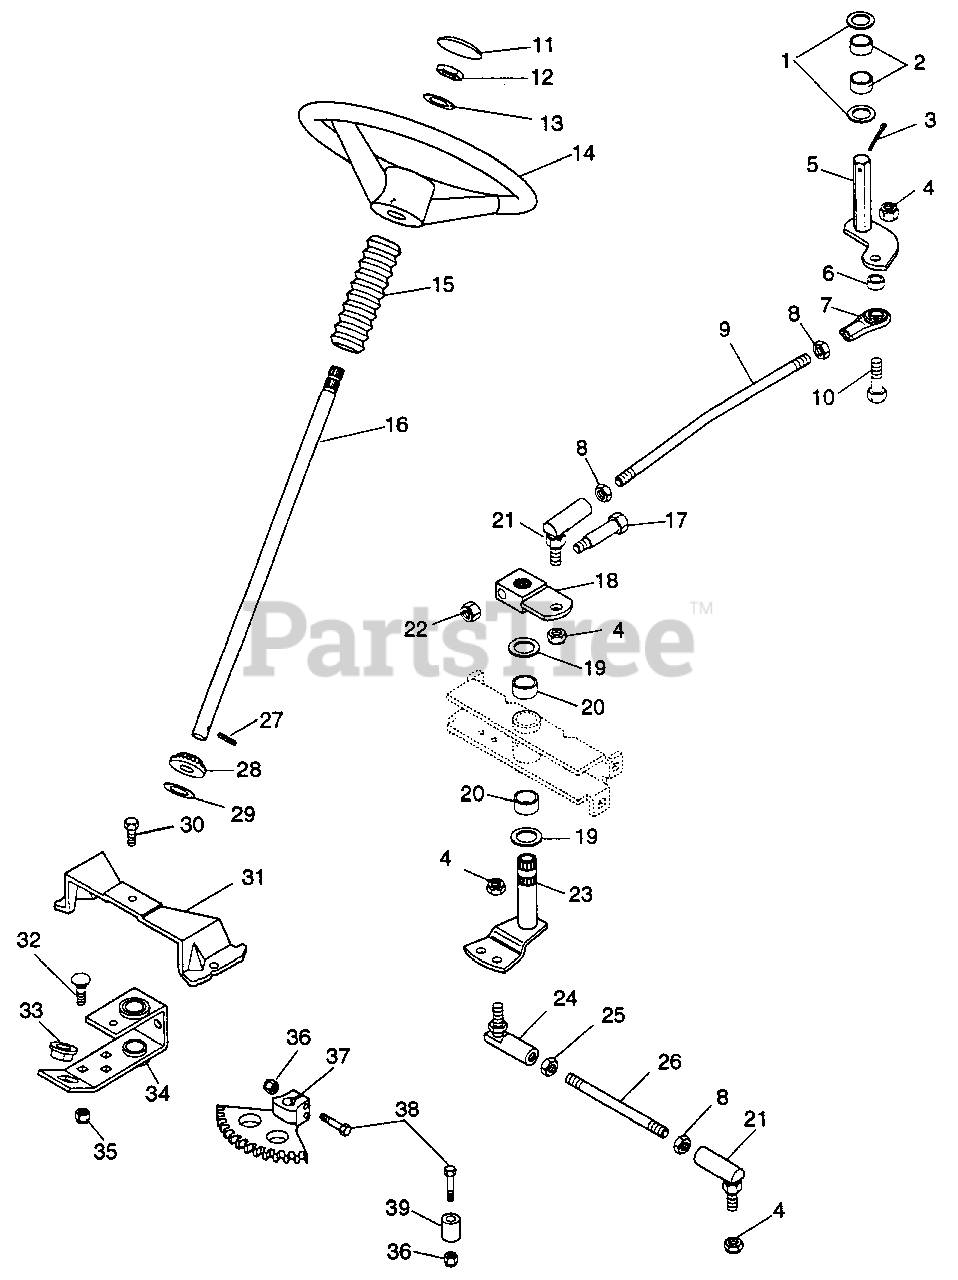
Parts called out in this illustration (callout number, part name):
1	Wshr-Thrst .877 x 1.427 x .032
2	Bshg-Slv .750 x 1.000 x .760 Hx Sb
3	Pin-Cotr .188 x 1.25
4	Nut-Lk .50-20 Pl
5	Arm & Shaft
6	Spacer
7	Rod End
8	Nut-Jam .50-20 Pl
9	Steering Link
10	Blt-Hex .50-20 x 1.75 Pl Gr 5
11	Steering Wheel Cap
12	Nut-Jam .625-11 Pl
13	Wshr-Fl-Stl .656 x 1.312 x .095 Pl
14	Steering Wheel
15	Steering Column Boot
16	Steering Column
17	Lock Bolt
18	Arm
19	Plastic Washer
20	Bshg-Slv 1.000 x 1.125 x .875
21	Ball Joint 75
22	Nut-Lk-Nyl .50-13 Pl
23	Steering Pivot
24	Ball Joint, L.H. 150
25	Nut-Jam .50-20 LH Thd Pl
26	Tie Rod
27	Pin, Spring 1/4 x 1 1/8
28	Pinion Gear-Steering
29	Wshr-Thrst .752 x 1.240 x .062 Hdn
30	Blt-Hex .38-16 x 1.00 Pl Gr 5
31	Steering Support Brace
32	Blt-Rdhdsqnk .38-16 x 1.0 Pl
33	Bshg-Flg .750 x 1.093 x .625 x 1.375
34	Steering Bracket
35	Nut-Lk-Nyl .375-16 Pl
36	Nut-Lk-Nyl .312-18 Pl
37	Steering Bevel Gear
38	Blt-Hex .31-18 x 1.75 Gr 5
39	Spacer
